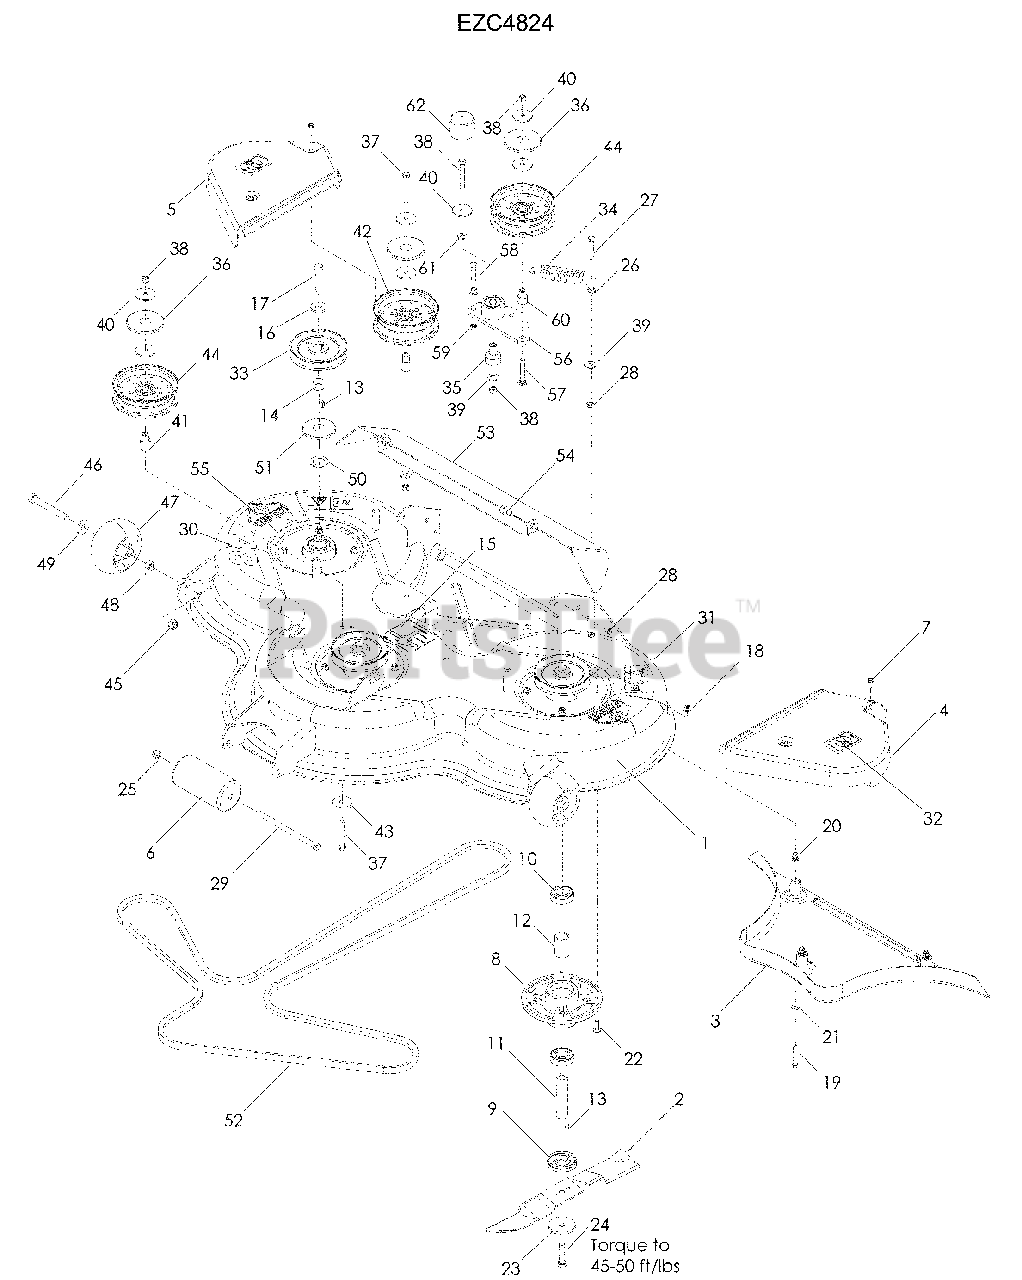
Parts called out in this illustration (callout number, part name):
1	DECK w/DECALS
2	BLADE
3	PLUG, MULCH
4	BELT SHIELD, LT
5	BELT SHIELD, RT
6	ROLLER
7	SCREW ¼-20 x 5/8 SLF TAP
8	HOUSING, BEARING
9	BUSHING, BLADE
14	KEY RETAINER
15	DECAL, BELT ROUTING
17	HCS M12 x 1.75 x 60 GR 8.8
18	NUT 5/16-18 FLANGE NYLOC
19	HCS M8 x 1.25 x 50 GR 8.8
21	WASHER 5/16 SAE FLAT
22	RHSNB 5/16-18 x 1
24	HCS M12 x 1.75 x 50 GR 8.8
25	NUT 7/16-14 HEX CTRLK GR A
26	NUT 3/8-16 HEX WHIZLK
27	HCS 3/8-16 x 2
28	NUT 3/8-16 HEX JAM NYLOC
29	HCS 7/16-14 x 7
31	DECAL, BELT DRIVES
32	DECAL, NO STEP
33	PULLEY, 48
35	PIVOT, BEARING
36	DUST CAP, TOP
37	HCS 3/8-16 x 2¾
38	NUT 3/8-16 HEX NYLOC
39	WASHER 3/8 FLAT STD
40	WASHER 3/8 SPECIAL
41	BUSHING, IDLER
42	PULLEY, IDLER
43	WASHER, HEAVY
44	PULLEY, IDLER
45	NUT ½ HEX NYLOC
46	HCS ½ -13 x 4
47	WHEEL, GAUGE
48	NUT ½-13 HEX
49	WASHER ½ FLAT
51	DUST CAP, BOTTOM
53	GUARD, DISCHARGE
54	BOLT 3/8-16 x 3/8 SKT HD
55	DECAL, CPSC
56	ARM, IDLER w/BEARINGS
57	BOLT 3/8-16 x 2½ CARRIAGE
58	HCS 3/8-16 x 1½ GR 8
59	NUT 3/8-16 HEX JAM
60	BUSHING, IDLER
61	WASHER 3/8 SAE FLAT
62	CAP, VINYL
